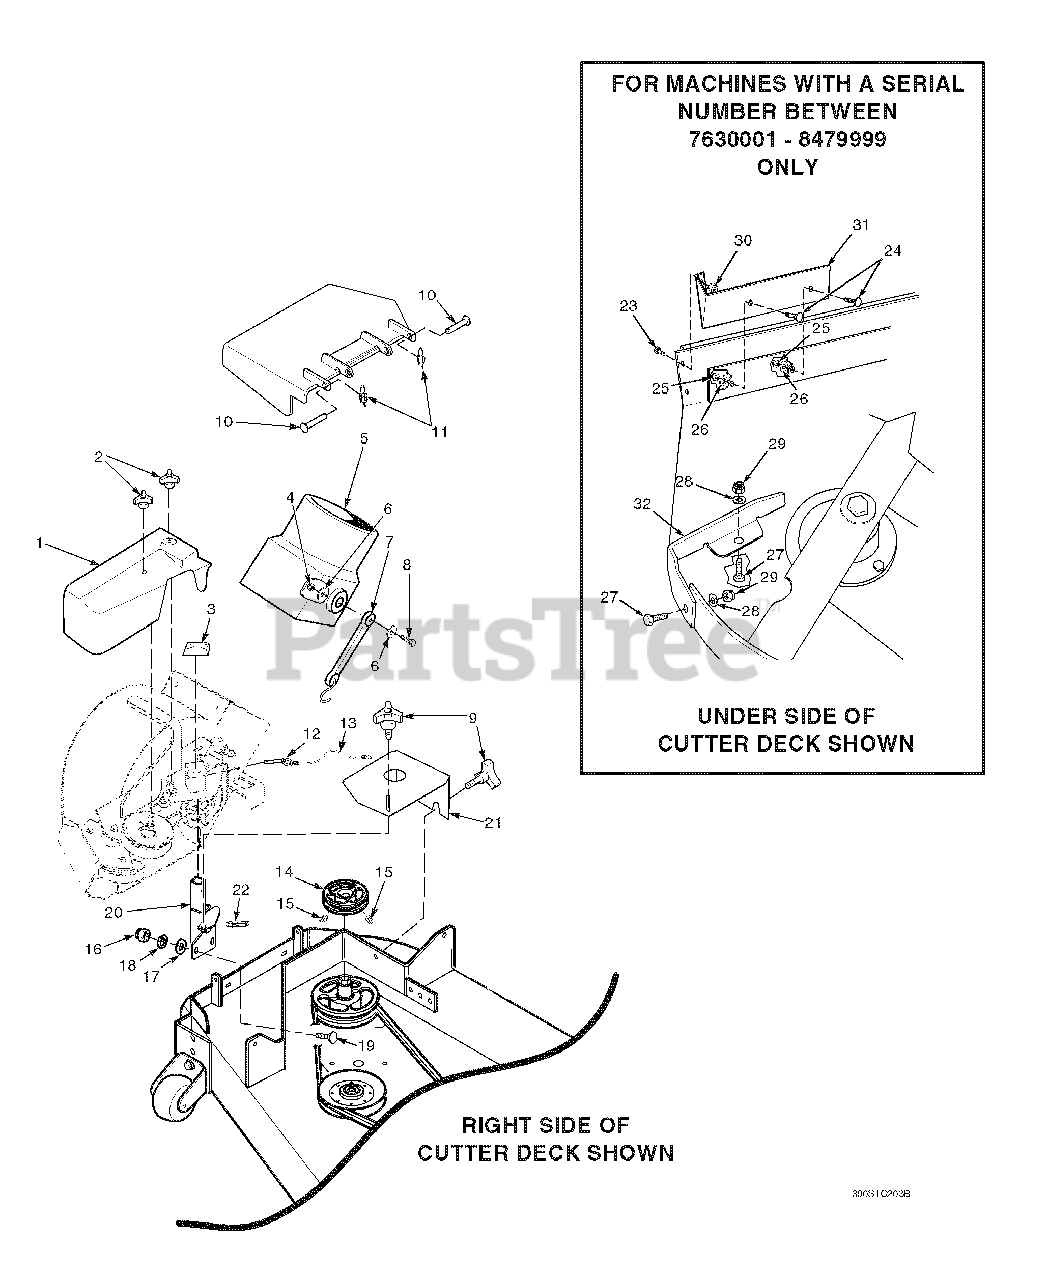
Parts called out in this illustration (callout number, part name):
1	Belt Cover, GC-STC
2	Wingnut, Plastic 3/8" Small
3	Cap, Square Vinyl
4	Nut, Elastic Stop 1/4-20
5	Adapter, Blower GC-STC
6	Flatwasher, 1/4-.312 x .750 x .065
7	Rubber Strap 7-3/4"
8	Bolt, Hex Head 1/4-20 x 1-1/4"
9	Knob W/Stud, 3/8-16 x 1-1/4"
10	Clevis Pin, 5/16 x 1-1/2"
11	Pin, Rue Cotter 5/16 Dia.
12	Pin, Ring 1/2 x 2-1/4"
13	Lanyard
14	Pulley, 4.0" Dia. 1.125 Bore
15	Setscrew, 5/16-18 x 3/8"
16	Nut, Elastic Stop 3/8-16
17	Lockwasher, 3/8"
18	Flatwasher, 3/8-.391 x .938 x .105
19	Bolt, Carr. 3/8-16 x 1-1/4" Grade 5
20	Mounting Post Weldment, Blower
21	Belt Cover
23	Bolt, Hex Head 1/4-20 x 3/4"
24	Bolt, Carriage 3/8-16 x 1"
25	Nut, Elastic Stop 3/8-16
26	Flatwasher, 3/8-.391 x .938 x .105
27	Bolt, Hex Head 5/16-18 x 1"
28	Flatwasher, 5/16-.375 x .875 x .083
29	Nut, Elastic Stop 5/16-18
30	Nut, Serrated Flange 1/4-20
31	Baffle, 48"
32	Baffle, Turbo 48" Deck
